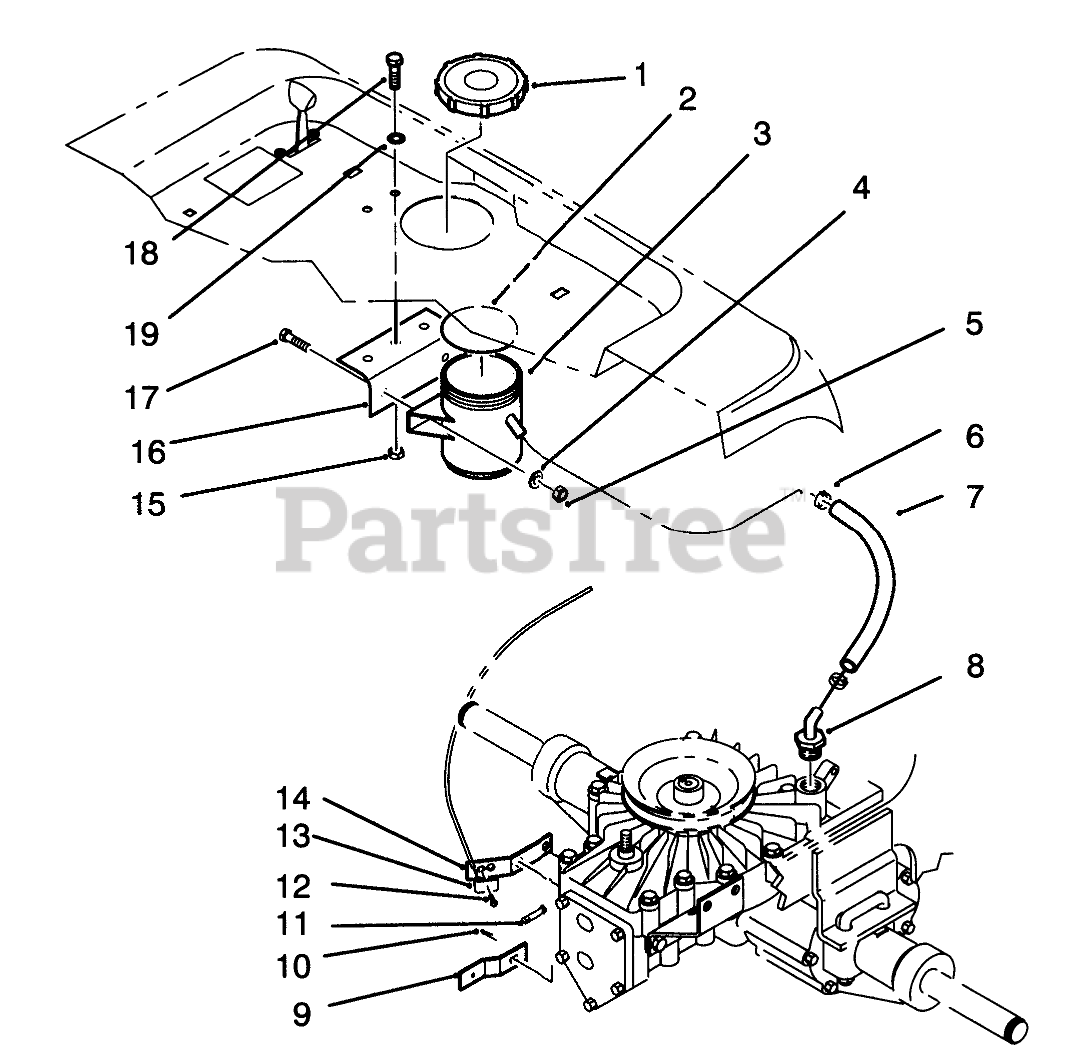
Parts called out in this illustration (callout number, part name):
1	COVER
2	COVER GASKET
3	RESERVOIR
4	WASHER-FLAT
5	NUT-LOCK, NI
6	CLAMP .875
7	HOSE-7"
8	HOSE BARB
9	Plate
10	Cotter Pin
12	Screw
13	CLAMP THROTTLE
14	PLATE-MTG
15	NUT-LOCK, NI
16	BRACKET R
17	SCREW-HH
18	SCREW-HH
19	WASHER-PLAIN
